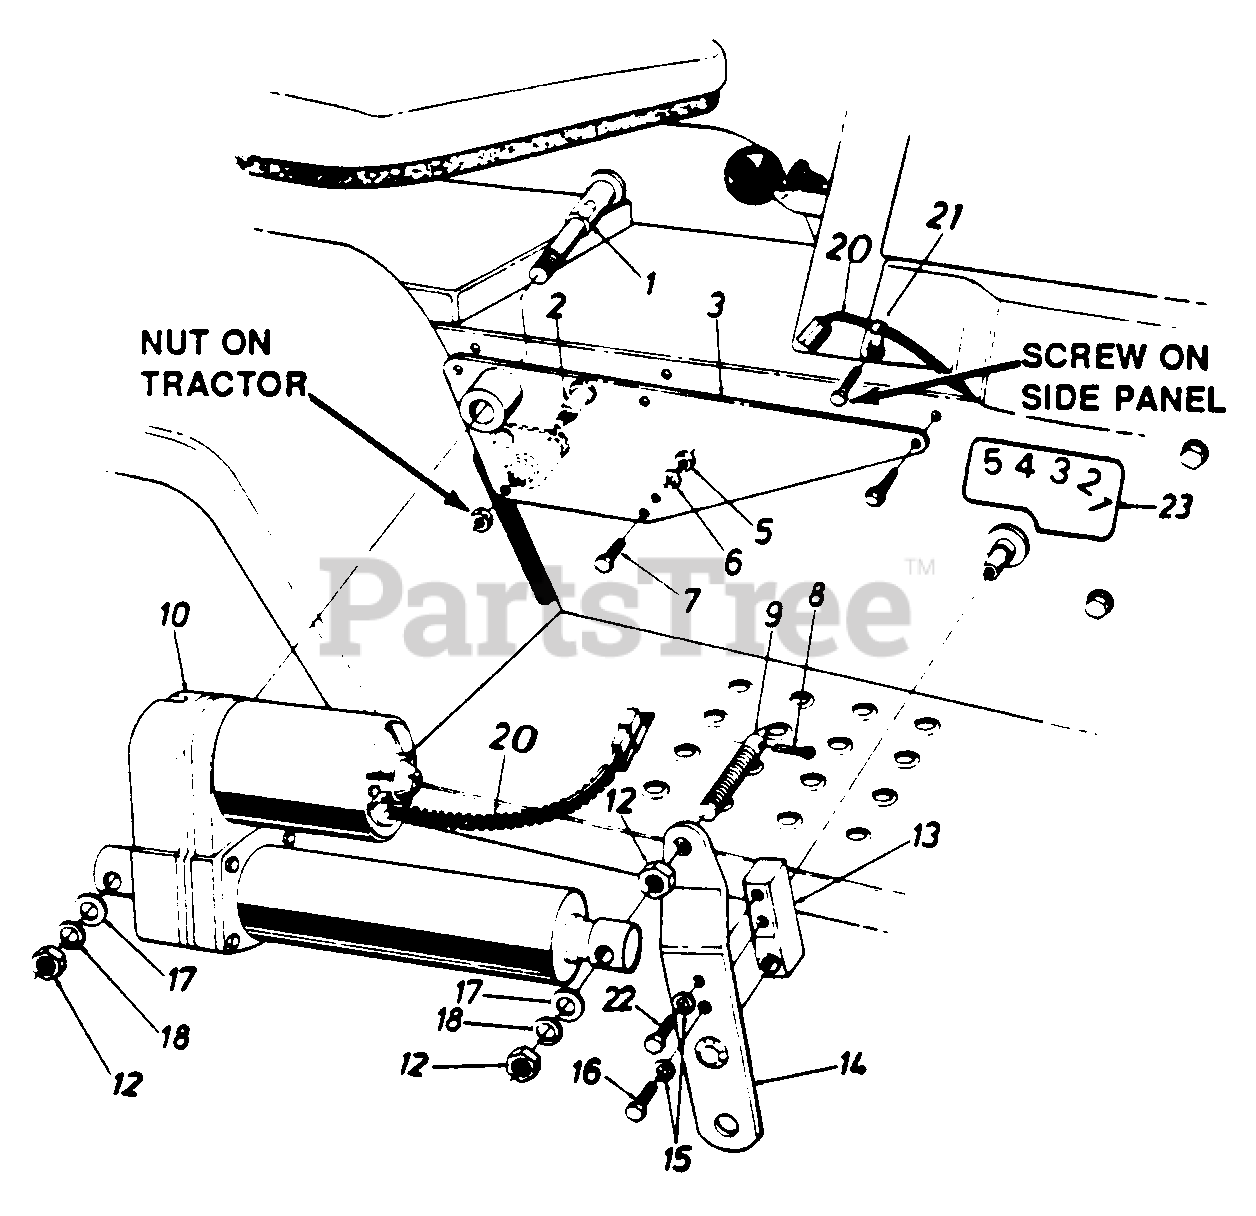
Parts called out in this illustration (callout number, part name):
2	Shld. Bolt .626 Dia. x .96
6	L-Wash. 1/4-I.D.
7	Hex Bolt 1/4-28 x .75" Lg. (Gr. 5)
9	Indkator & Mtg. Pin
10	Electric Actuator
12	Hex Jam Nut 1/2-13 Thd.
13	Litt Shaft Drive
16	Hex Bolt 5/16 24 x 1.0" Lg. (Gr. 5)
17	Fl-Wash. .53 I.D. x .93 O.D.
18	L-Wash. 1/2 I.D.
20	Plastic Harness
22	Hex Bolt 5/16-18 x 1" Lg. (Gr. 5)
23	Label
